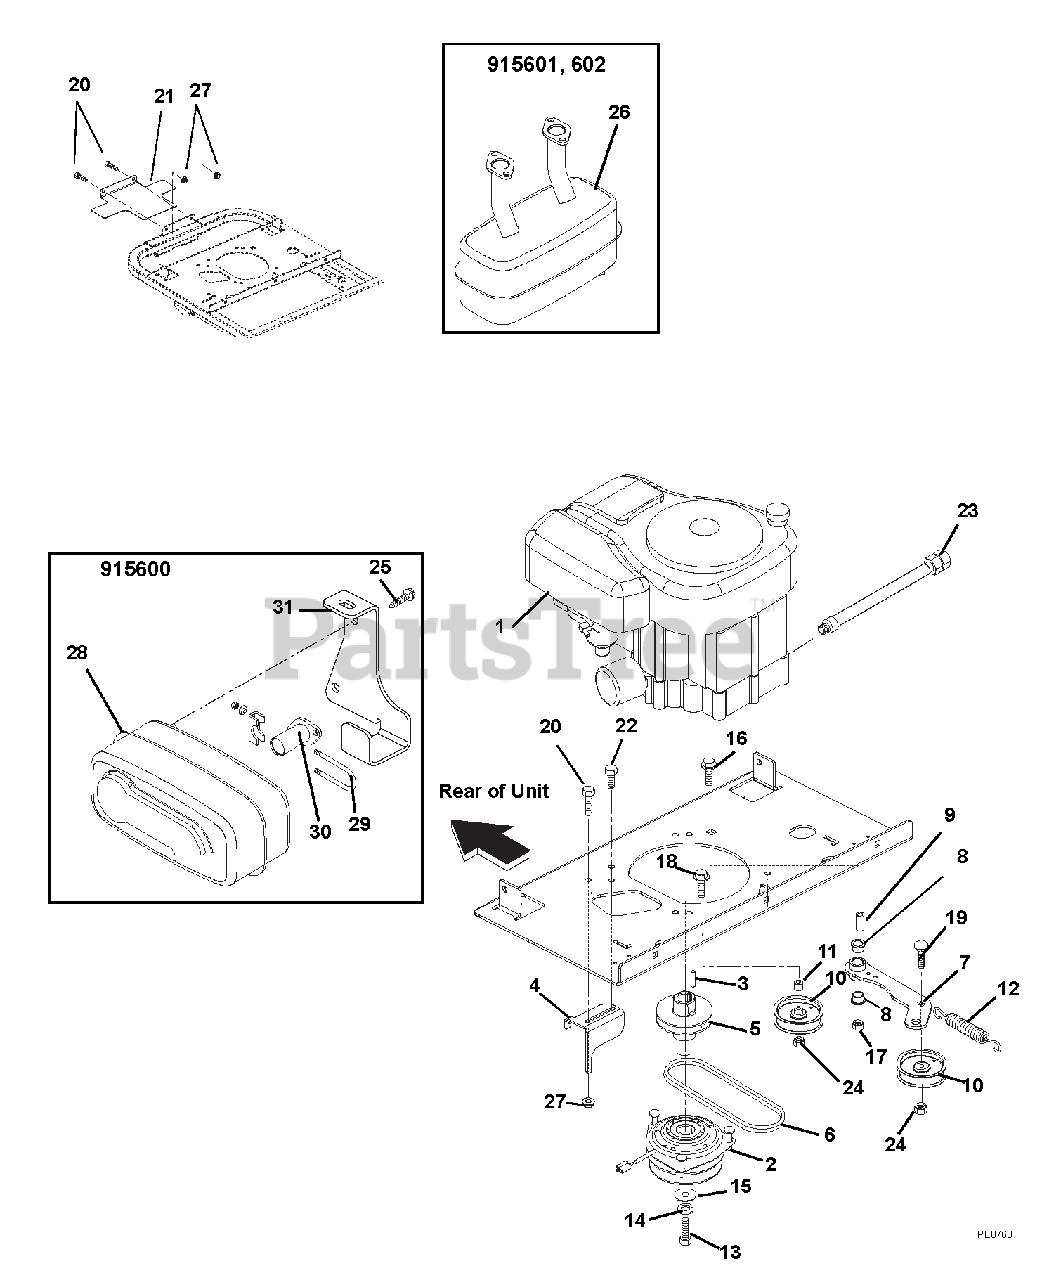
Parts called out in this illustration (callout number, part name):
1	ENGINE, 18 HP KOHLER SINGLE
1	ENGINE, 20 HP KOHLER COUR TWIN
1	ENGINE, 23 HP KOHLER COUR TWIN
2	CLUTCH,ELECTRIC PTO
3	KEY-SQ .25 X 1.50 X .25 SAE
4	STOP, CLUTCH
5	EXTENSION, CRANK SHAFT
6	BELT,HA WRAPPED
7	WMT, IDLER ARM
8	BSHG-FLG 0.75X0.875X.625X1.125
9	BSHG-SLV .500X.750X1.560
10	IDLER-FLAT 4.00 X .38 NWHAMSHR
11	BSHG,SPCR .41 X .75 X .88 PM
12	SPRING, EXT
13	BLT-HEX .44-20X4.50 GR8 YWZC
14	@WSHR-LK .44X.109 REG YWZC
15	WSHR-FL-STL .469X2.00X.25 YWZC
16	@BLT-HEX .50-13X2.50 GR5 YWZC
17	@NUT-LK-TOP-FLG .50-13 YWZC
18	@BLT-RDHDSQNK .38-16X2.00 G5YZ
19	@BLT-RDHDSQNK .38-16X1.25 G5YZ
20	@BLT-HEX .38-16X1.00 GR5 YWZC
21	HEAT SHIELD, TWIN
22	@SCR-TAP .38-16X1.00 HWH TR YZ
22	@BLT-HEX .38-16X1.00 GR5 YWZC
23	HOSE, HYD .38-15-0K M6N0-F6J0
24	@NUT-LK-CTR-JAM .375-16 YWZC
25	@SCR-TAP .25-20X.50 HWH TR YWZ
26	MUFFLER, TWIN KOHLER (EES)
27	@NUT-LK-NYL-FLG .38-16 YWZC
28	MUFFLER, KOHLER SINGLE
29	MUFFLER CLAMP
30	WMT, MANIFOLD
31	BRKT, MUFFLER (KOHLER COURAGE)
32	@SCR-TAP .38-16X1.00 HWH TR YZ
